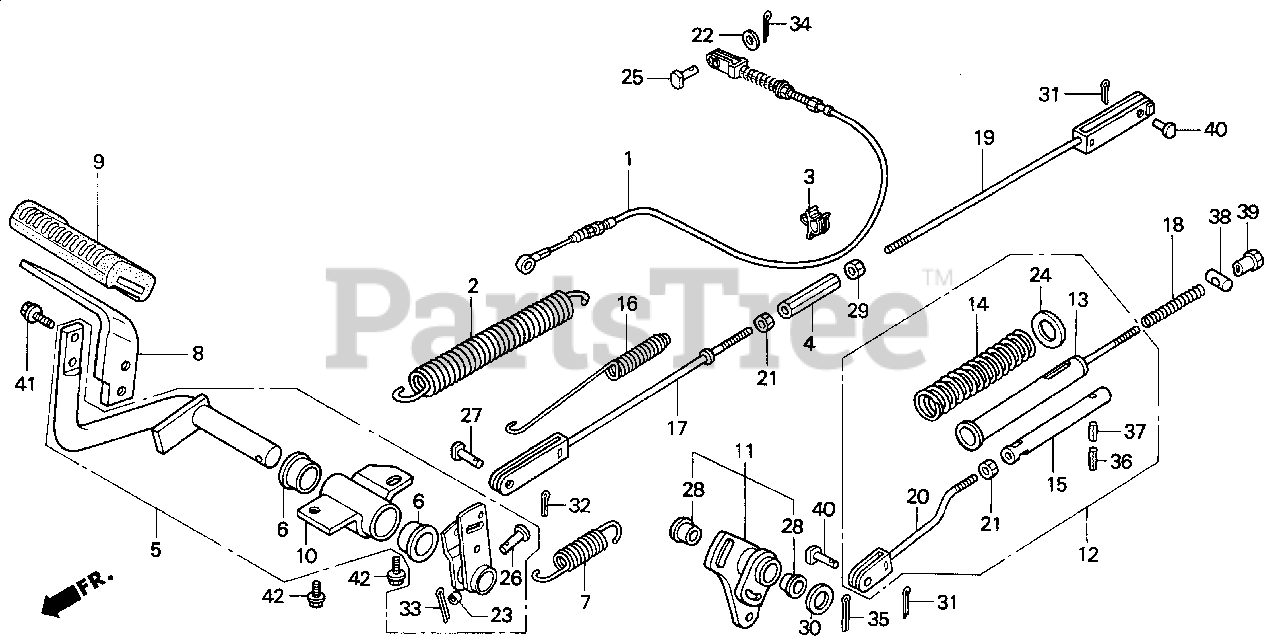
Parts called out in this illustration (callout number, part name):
1	CABLE, CLUTCH
2	SPRING, CLUTCH
3	CLIP, WIRE HARNESS
4	JOINT (6MM)
5	ARM ASSY., BRAKE PEDAL
6	BUSH, BRAKE PEDAL
7	SPRING, BRAKE PEDAL
8	BRACKET, BRAKE PEDAL
9	RUBBER, BRAKE PEDAL
10	PIVOT, BRAKE PEDAL
11	ARM ASSY., BRAKE ROD
12	PIPE ASSY., FOOT BRAKE
13	PIPE, FOOT BRAKE SPRING SETTING
14	SPRING, FOOT BRAKE LOAD SETTING
15	SHAFT, SPRING SET
16	SPRING, BRAKE DAMPER
17	ROD A, RR. BRAKE
18	SPRING A, BRAKE ROD
19	ROD B, RR. BRAKE
20	ROD, RR. BRAKE (C)
21	NUT, GOVERNOR ARM FIXING
22	WASHER (8MM)
23	COLLAR (10X5)
24	WASHER, BRAKE SPRING SETTING
25	PIN (8X17.5)
26	PIN, BRAKE SHAFT
27	PIN (5.3X17)
28	BUSH (16X18X15)
29	NUT, HEX. (6MM)
30	WASHER, PLAIN (16MM)
31	PIN, COTTER (1.6X12)
32	PIN, COTTER (2.0X12)
33	PIN, COTTER (2.0X15)
34	PIN, COTTER (2.0X22)
34	PIN, COTTER (2.0X35)
35	PIN, COTTER (3.0X45)
36	PIN, SPRING (3X28)
37	PIN, SPRING (5X28)
38	JOINT A, BRAKE ARM
39	NUT A, BRAKE ROD ADJUSTING
40	PIN B, BRAKE ROD JOINT
41	BOLT, FLANGE (8X18)
42	BOLT, FLANGE (10X18)
